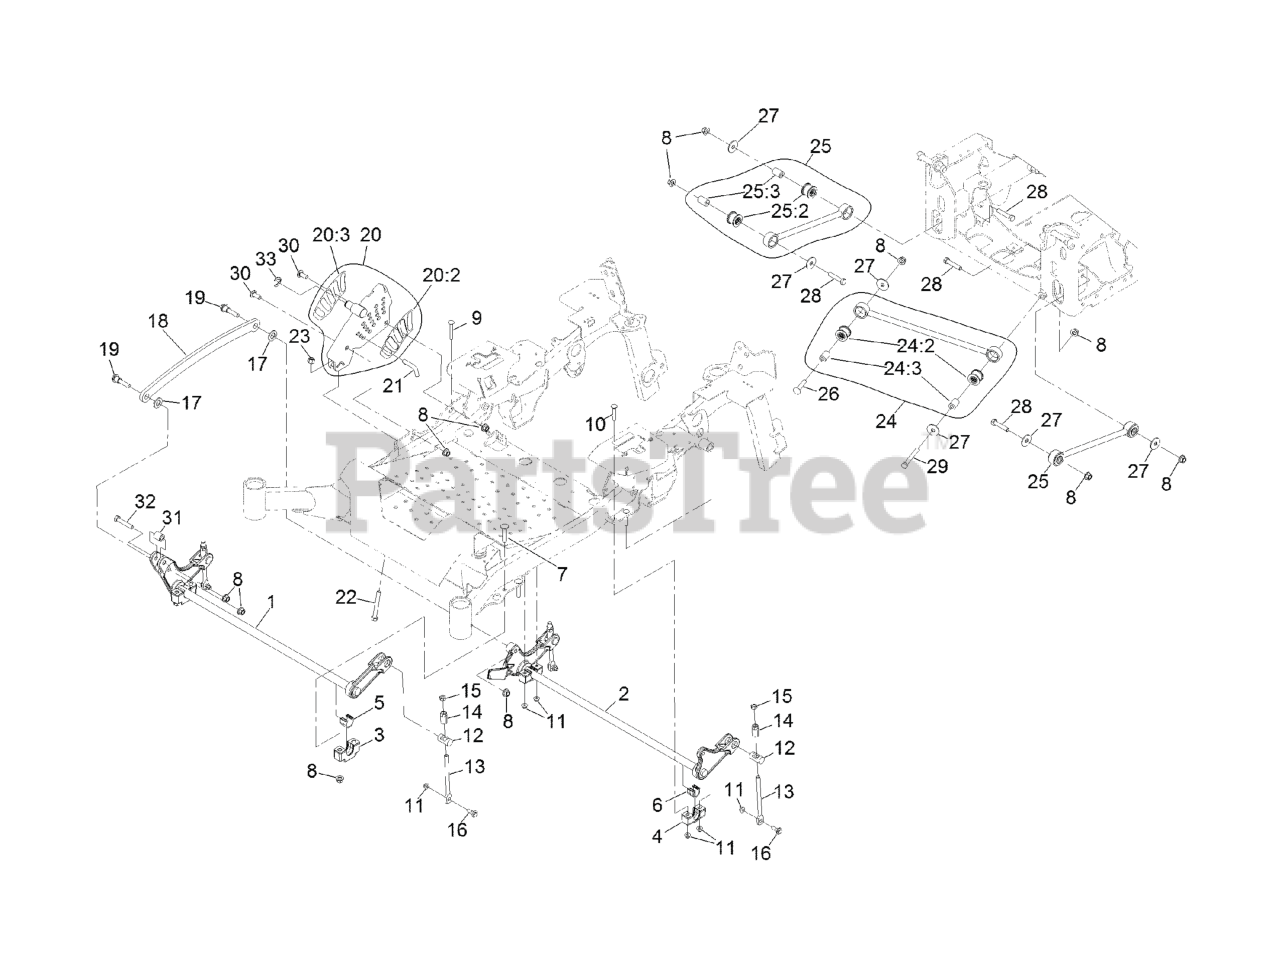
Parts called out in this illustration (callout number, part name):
1	DECKLIFT-FRONT
2	LIFT-DECK, REAR
3	SUPPORT-CROSS SHAFT, BEARING
4	SUPPORT-CROSS SHAFT, BEARING REAR
5	BEARING-CROSS SHAFT, FRON
6	BEARING-CROSS SHAFT, REAR
7	Bolt-Carriage 1/2-13 X 2 1/2 Spl Neck
8	Nut-Lock 1/2-13
9	SCREW-CARR
10	Bolt-Carriage 3/8-16 X 2 1/4
11	NUT-HF, NI
12	TRUNNION
13	LINK-ADJUSTER, DECK LIFT
14	ADJUSTER-LIFT, DECK
15	NUT-JAM
16	SCREW-SHOULDER, HHF
17	WASHER-FLAT
18	LINK-LIFT, DECK
19	SCREW-HHF, SHOULDER
20	HOC ASM
20:2	DECAL-HEIGHT OF CUT
20:3	DECAL-HEIGHT OF CUT, OUTER
21	PIN-HOC
22	BOLT-TAP
23	NUT-LOCK, NI
24	PANHARD ROD ASM
24:2	BUSHING-SUSPENSION, RUBBER
25	DECK STRUT ASM
25:2	BUSHING-SUSPENSION, RUBBER
26	SCREW-CARR
27	WASHER-THRUST
28	SCREW-HH
29	SCREW-HH
30	SCREW-CARR, SHORT NECK
31	SPACER-PIVOT
32	SCREW-HH
33	RING-RETAINING
